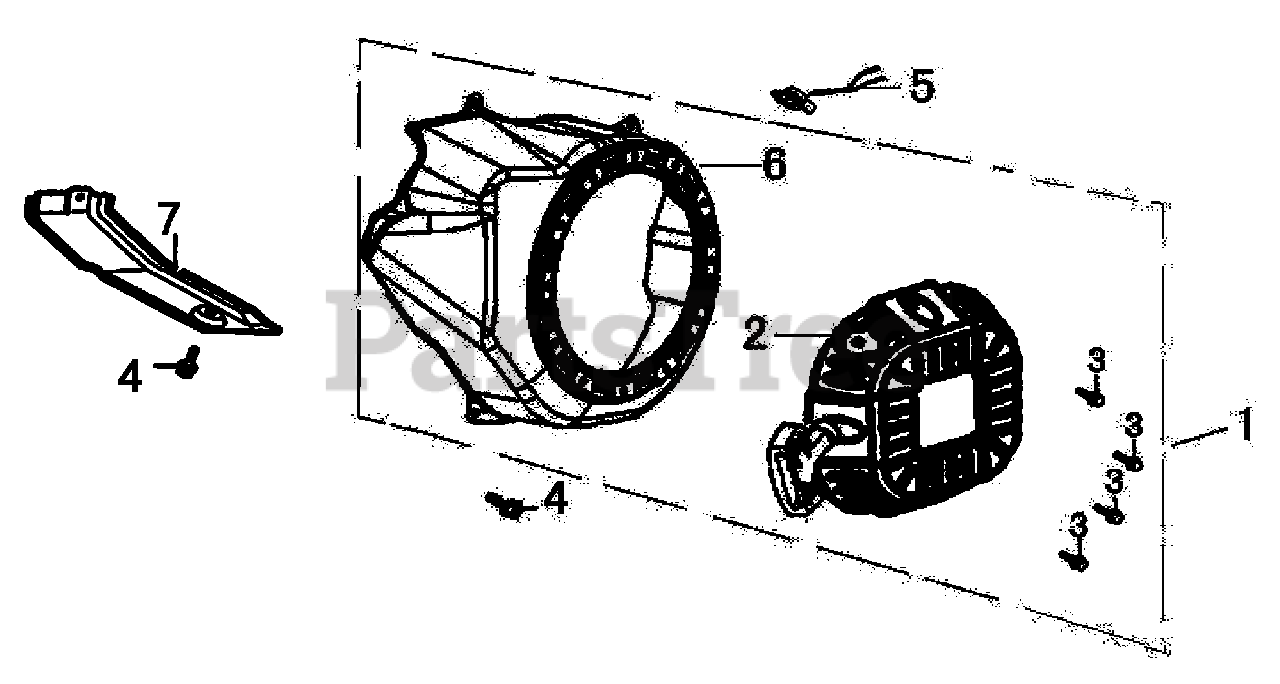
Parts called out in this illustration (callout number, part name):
1	STARTER, RECOIL W/HOUSING
2	STARTER ASSY., RECOIL
3	BOLT,FLANGE 6X8
4	BOLT,FLANGE 6X12
5	SWITCH ASSY.,ENGINE STOP
6	HOUSING, FAN BLOWER
